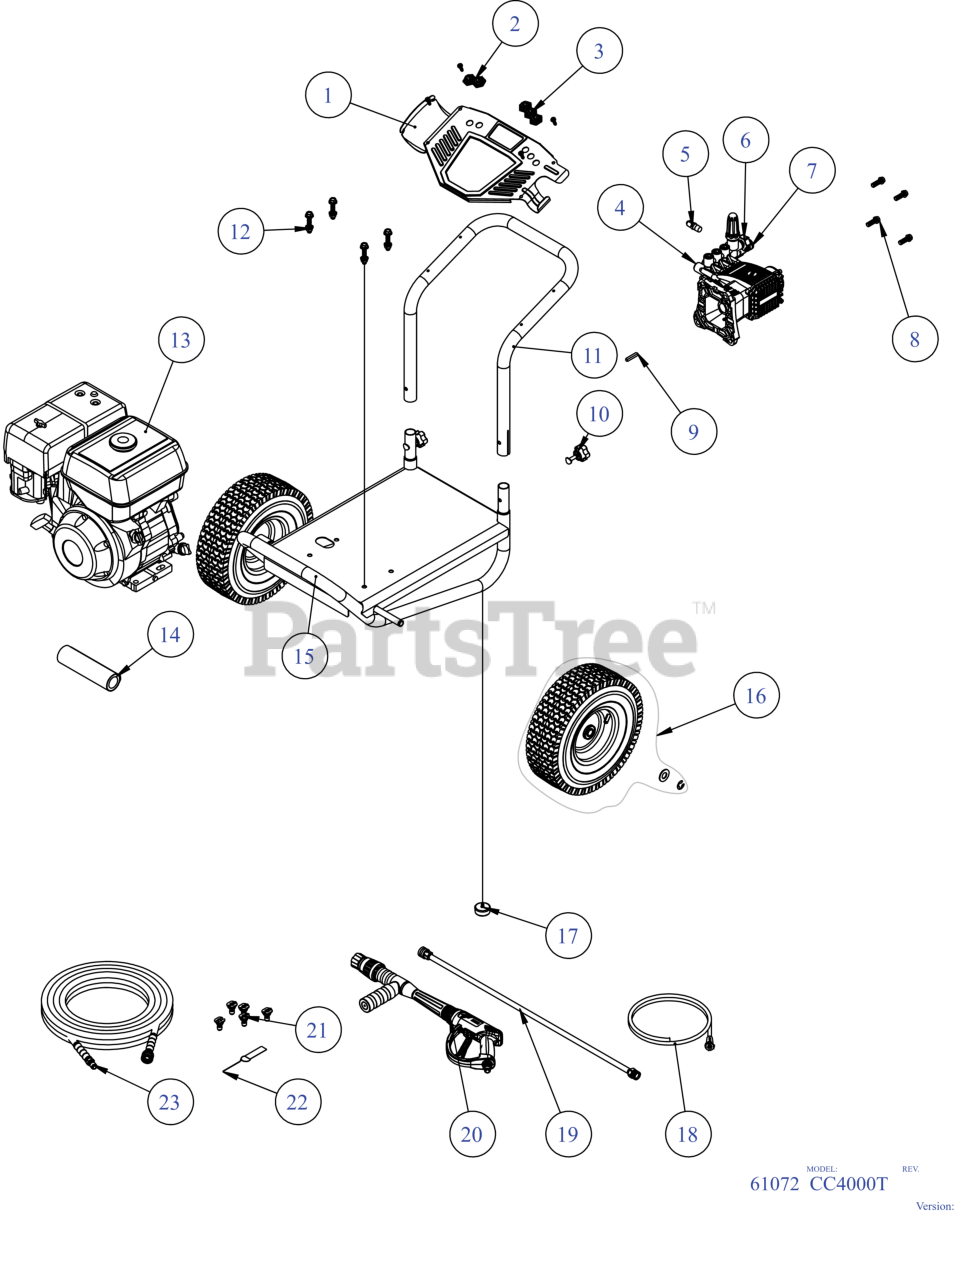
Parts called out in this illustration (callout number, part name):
1	DASHBOARD SVC ASSY
2	HOLDER-NOZZLE 2 PC
3	HOLDER-NOZZLE 3 PC
4	PUMP ASSEMBLY
5	VALVE-THERMAL RELIEF
6	INLET CONNECTION KIT
7	QUICK CONNECT OUTLET
8	PUMP MOUNTING HARDWARE
9	KEY: SHAFT 1/4" x 1/4" x 1.5"
10	KNOB-HANDLE MTG
11	TUBE, HANDLE BENT PUNCHED CUB CADET
12	ENGINE MOUNTING KIT
13	ENGINE, SVC ASSY HONDA GX270 W/LABELS
14	GRIP-HANDLE
15	FRAME, BASE WELDMENT CUB CADET
16	13" WHEEL (BEIGE)
18	HOSE-SOAP W/FILTER
19	WAND-SPRAY GUN 31"
20	GUN-SPRAY DIAL-N-WASH
21	NOZZLE SET-5 PIECE
22	TOOL-NOZZLE CLEANING
23	HOSE-SPRAY GUN 50'
